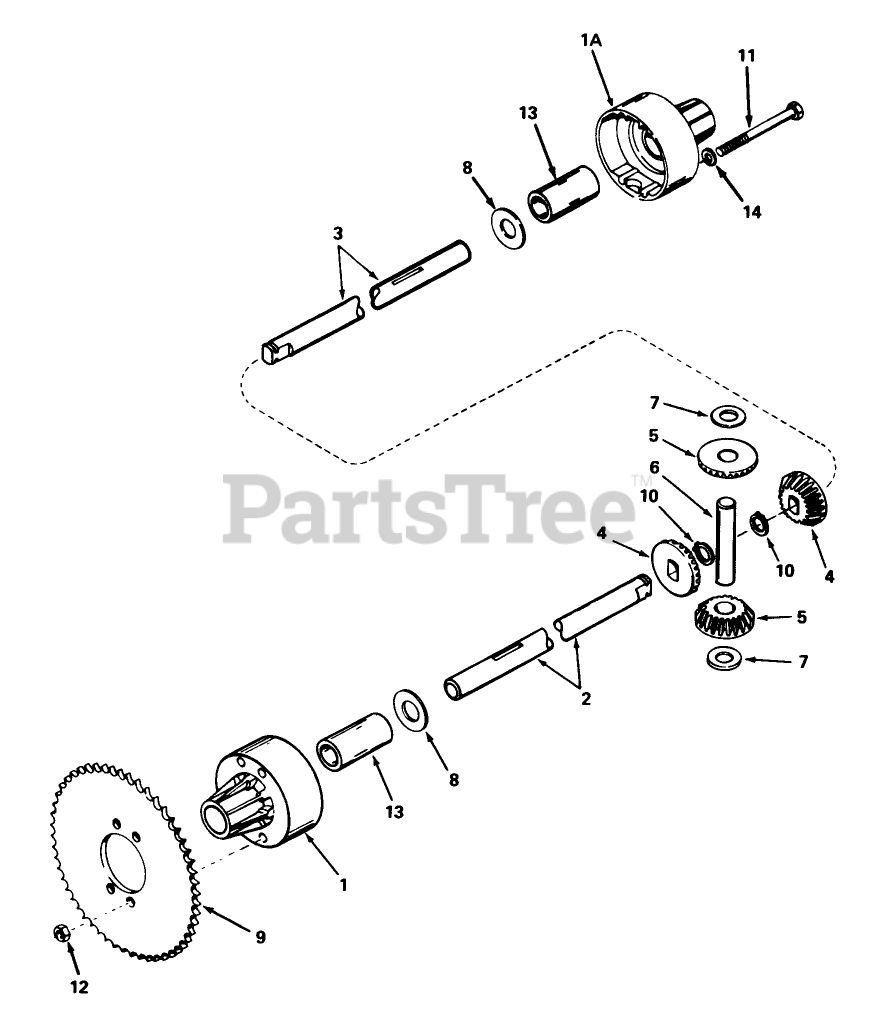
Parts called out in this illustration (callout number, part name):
1	Housing, Differential Carrier (Incl. Ref. #13)
1A	Housing, Differential Carrier (Incl. Ref. #13)
2	Axle (9-1/8" Long)
3	Axle (18-5/8" Long)
4	Bevel Gear
5	Gear Pinion
6	Pin Drive
7	Washer Thrust
8	Washer
9	Sprocket
10	Ring-Snap
11	Screw-Hex Hd.
12	Nut-Lock
13	Bushing
14	Washer
